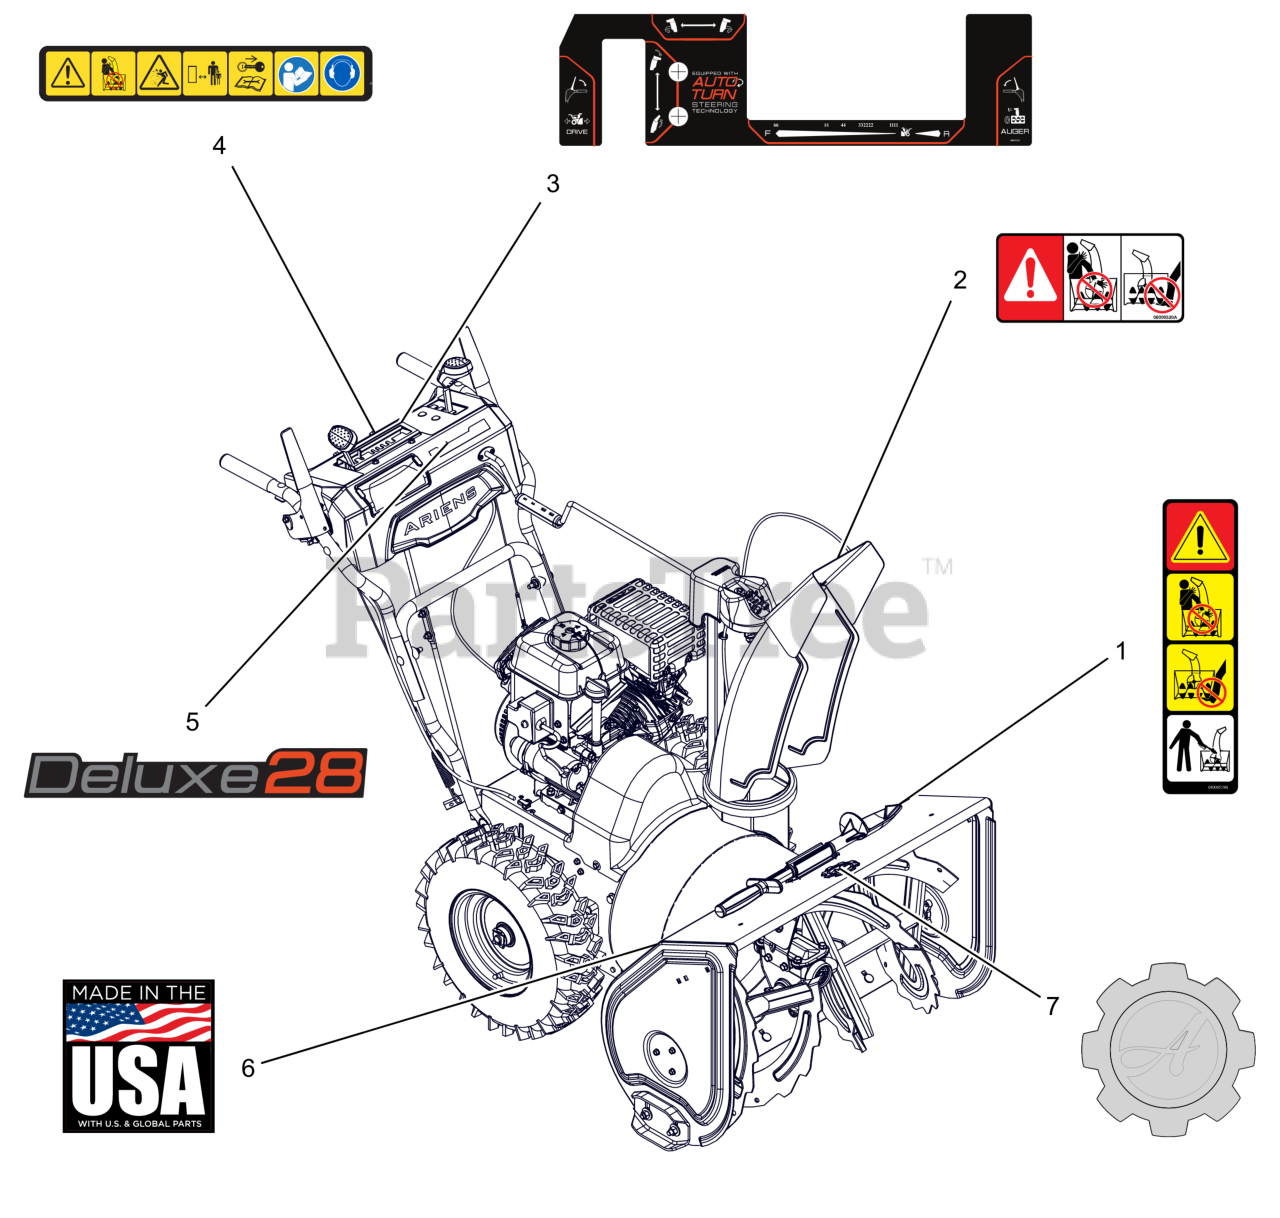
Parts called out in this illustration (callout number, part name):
1	DECAL, DANGER - ROTATING PARTS
2	DECAL, DANGER
3	DECAL,CONTROL-SML,AT,ID
4	DECAL,DASH - SAFETY
5	DECAL, DASH - DELUXE 28
6	DECAL, MADE IN USA
7	DECAL, ARIENS-GEAR BADGE -THK
